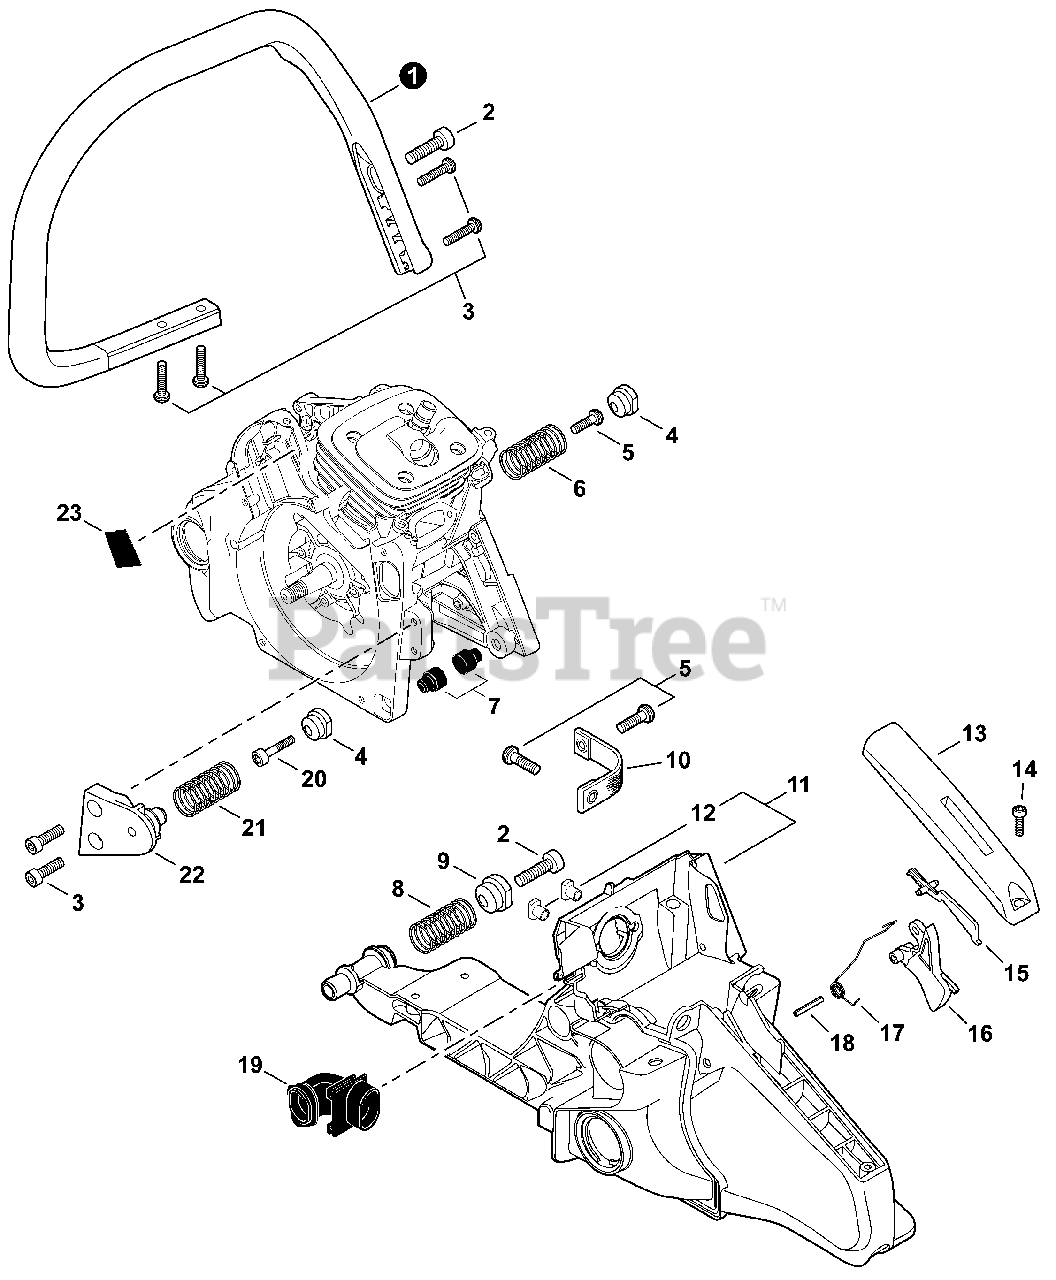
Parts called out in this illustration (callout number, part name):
1	HANDLE, FRONT
2	BOLT, TORX 6×20
3	BOLT, TORX 5×20
4	HOLDER, SPRING Ø14.4
5	BOLT, TORX 5×16
6	SPRING, COMPRESSION Ø17×38.4×2.6
7	CUSHION
8	SPRING, COMPRESSION Ø20×40×3.3
9	HOLDER, SPRING Ø17
10	STRAP, SAFETY
11	HANDLE, REAR
13	COVER, HANDLE
14	BOLT, TORX 4×12
15	LEVER, THROTTLE LOCKOUT
16	TRIGGER, THROTTLE
17	SPRING, TORSION
18	PIN, SPRING 4×25 SUS
19	PIPE, AIR INTAKE
20	BOLT, TORX 5×25
21	SPRING, COMPRESSION Ø17×36.7×2.6
22	HOLDER, SPRING
23	CUSHION
